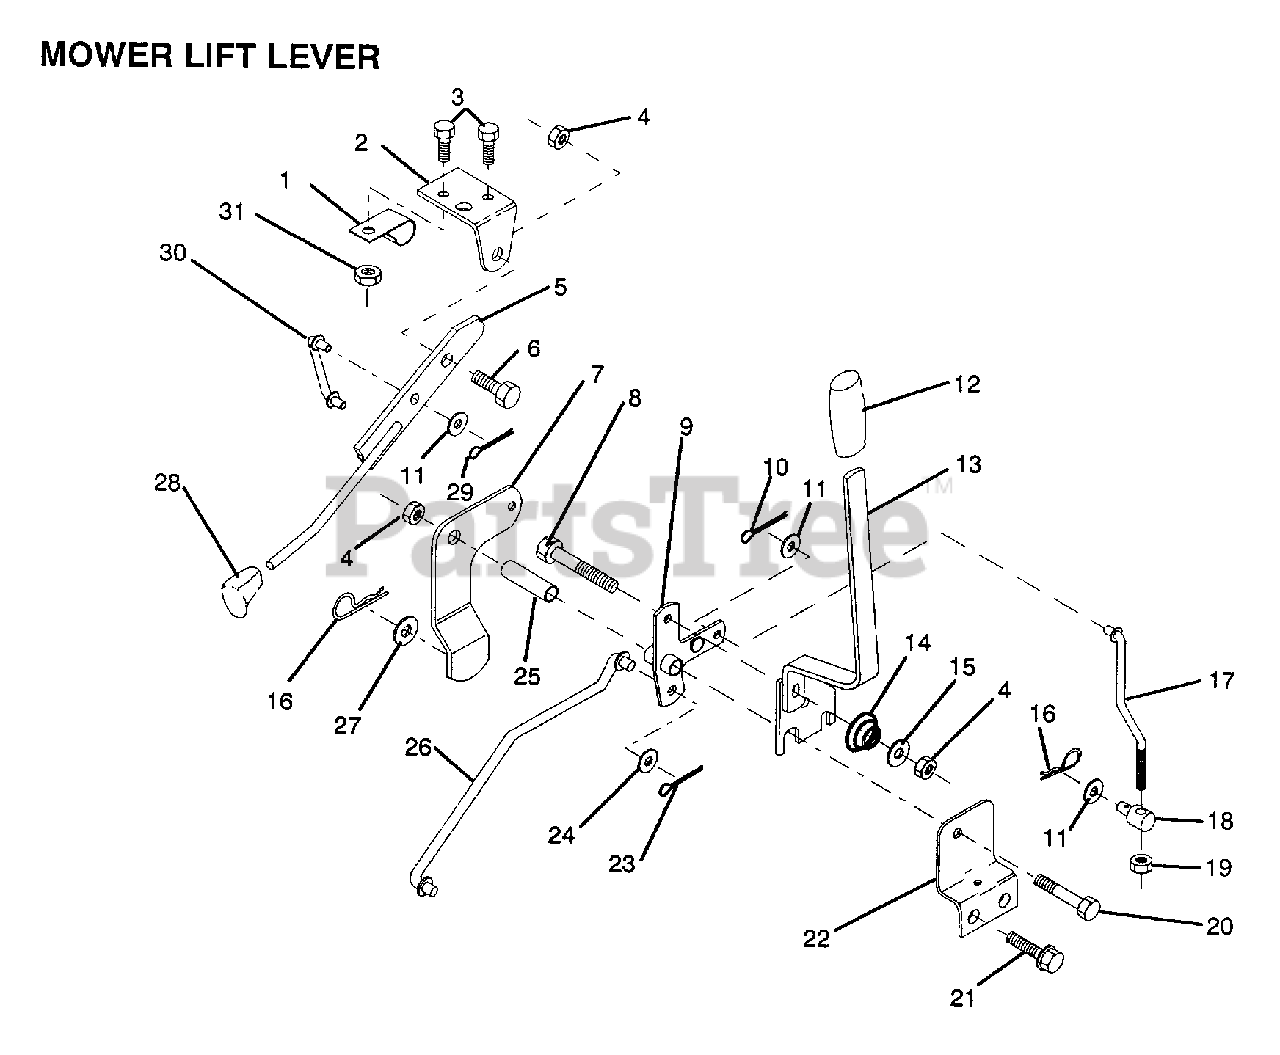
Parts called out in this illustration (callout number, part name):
1	"CLIP,INSULATOR"
2	BRKT CLUTCH
3	BOLT
5	CLUTCH LEVER AS
6	"BOLT, SHOULDER LT"
7	CLUTCH ARM ASS'Y
8	BOLT
9	"BELLCRANK,LIFT"
10	COTTER PIN
11	WASHER
12	GRIP HANDLE
13	"HDLE,LIFT T"
14	SPRING COMPRESSIO
15	WASHER T
16	SPRING.RETAINER
17	LINK FRT LIFT
19	NUT
20	BOLT
21	SCREW LT
22	"BRKT,MOWER HGT"
23	PIN COTTER 1/8
25	TUBE SPACER
26	"ROD,MOWER LIFT "
27	WASHER
28	KNOB
30	"LINK,MOWER LIFT"
